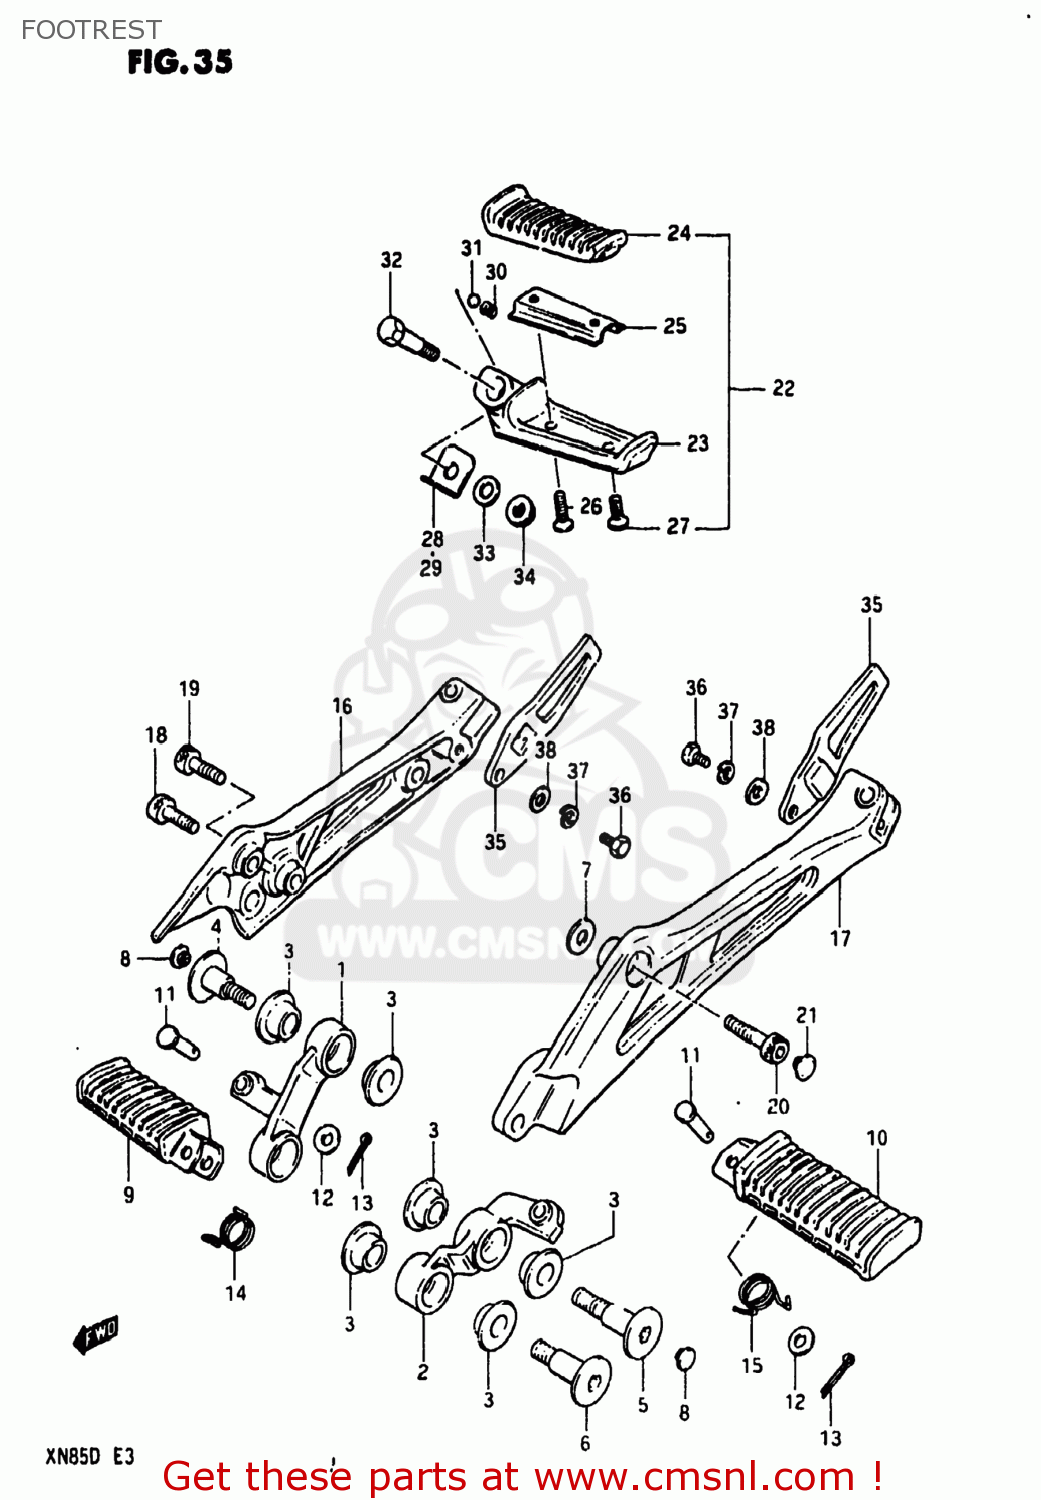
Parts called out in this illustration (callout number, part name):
1	BAR,FRONT FOOTREST,RIGHT
2	BAR,FRONT FOOTREST,LEFT
3	BUSH
4	BOLT
5	BOLT
6	BOLT
7	WASHER(10.5X28X2.3)
8	CAP
9	RUBBER,FOOTREST
10	FOOTREST
11	PIN
12	WASHER
13	PIN 20X20
14	SPRING
15	SPRING
16	BRACKET,MUFFLER,RIGHT
17	BRACKET,MUFFLER,LEFT
18	BOLT
19	BOLT
20	SCREW
21	CAP
22	FOOTREST ASSY,PILLION,R
23	BAR,PILLION FOOTREST,LEFT
24	RUBBER,PILLION FOOTREST
25	PLATE,RUBBER STOP
26	SCREW
27	SCREW 5X12
28	PLATE,SPRING STOP,R
29	PLATE,SPRING STOP
30	SPRING
31	BALL
32	BOLT
33	WASHER 6MM
34	NUT
35	GUARD,REAR FOOT
36	BOLT
37	LOCK WASHER
38	WASHER
